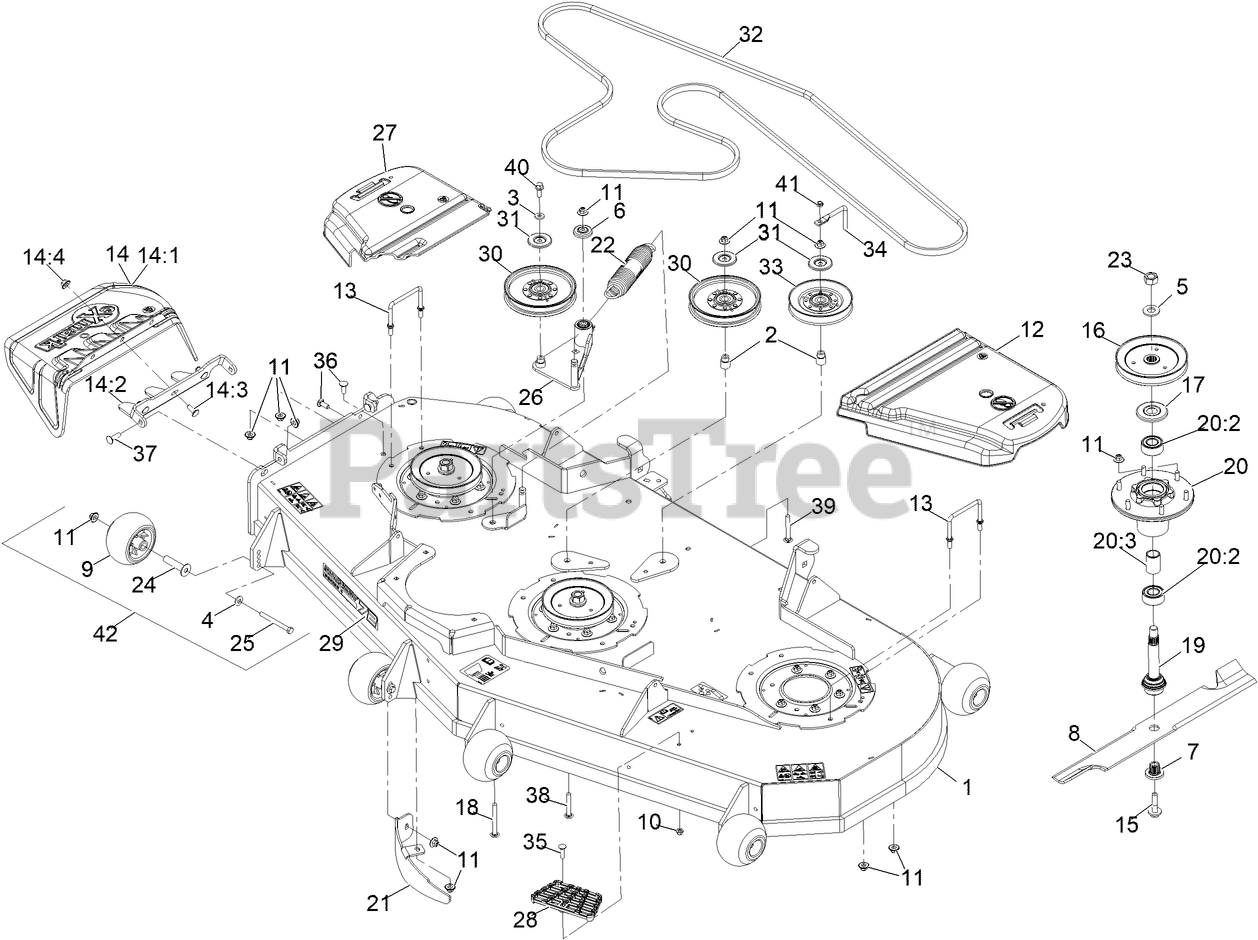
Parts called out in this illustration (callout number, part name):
1	BUSHING-IDLER
3	WASHER-BELLEVILLE
5	GUARD-TOP
6	BUSHING,SPLINED
8	ROLLER-SCALP, ANTI
9	NUT-HF, NI
10	Nut-Nyloc 3/8-16 Flg
11	COVER-BELT, LH
12	WIREFORM-COVER
13	ASM,DISCHARGE CHUTE
14	CHUTE,DISCHARGE
14:1	BRACKET,DISCHARGE CHUTE
14:2	SCREW-CARR
14:3	Nut-Nyloc 3/8-16 Flg
14:4	SCREW,SEMS 1/2-20 X 2.19
15	SHEAVE,BLADE DRIVE 6.50
16	GUARD-BEARING, TOP
17	BOLT-SHOULDER, CARRIAGE 3/8-16 X 3 1/2
18	ASM-SPINDLE AND SEAL
19	ASM-SPINDLE AND SEAL
20	ASM-CUTTER HSG
20:2	BEARING-3205 TRASHGUARD
20:3	SPACER-BEARING
21	BAFFLE-DOGLEG, LZ72
22	SPRING-EXTENSION
23	NUT-HEX
24	AXLE, ROLLER
25	SCREW-HH 3/8-16 X 3 3/4 GR 8
26	IDLER ARM ASM
27	SHIELD-BELT
28	STEP-DECK
29	DECAL, 724
30	IDLER-PULLEY
31	SHIELD-DUST
33	IDLER V
34	GUIDE-BELT
35	Bolt-Carriage 5/16-18 X 1 1/4
36	SCREW-CARR
37	Bolt-Carriage 3/8-16 X 1 1/4
38	SCREW-CARR
39	SCREW-CARR
40	SCREW-HHF
42	KIT, ANTI-SCALP ROLLER
